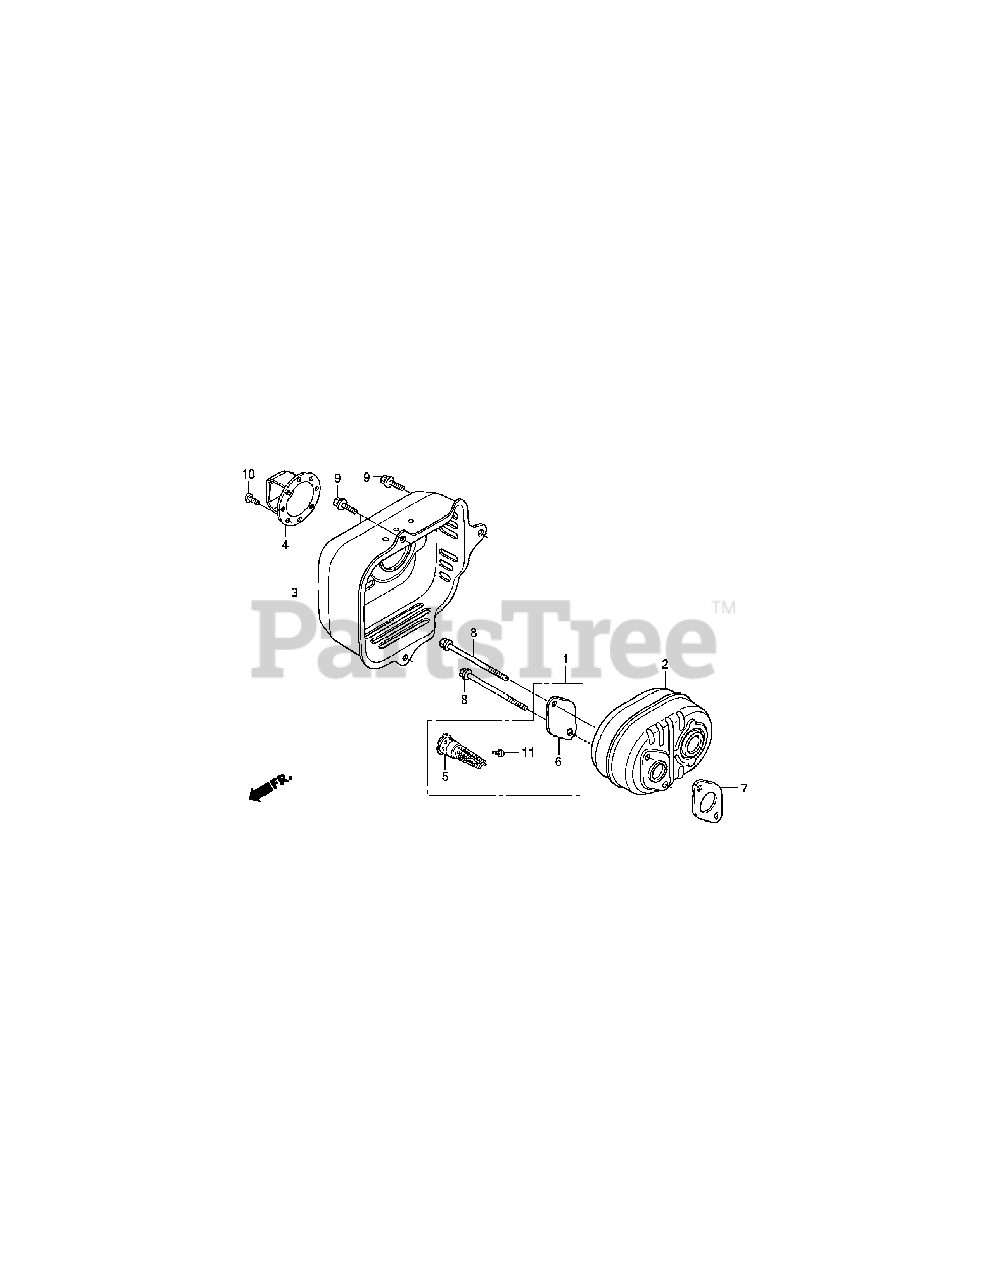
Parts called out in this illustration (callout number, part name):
1	Spark Arrester Kit
2	Muffler
3	Muffler Protector
4	Muffler Cap
5	Spark Arrester
6	Arrester Number Plate
7	Muffler Gasket
8	Flange Bolt, 6 x 79
9	Flange Bolt, 6 x 12
10	Tapping Screw, 4 x 6
11	Tapping Screw, 4 x 6
